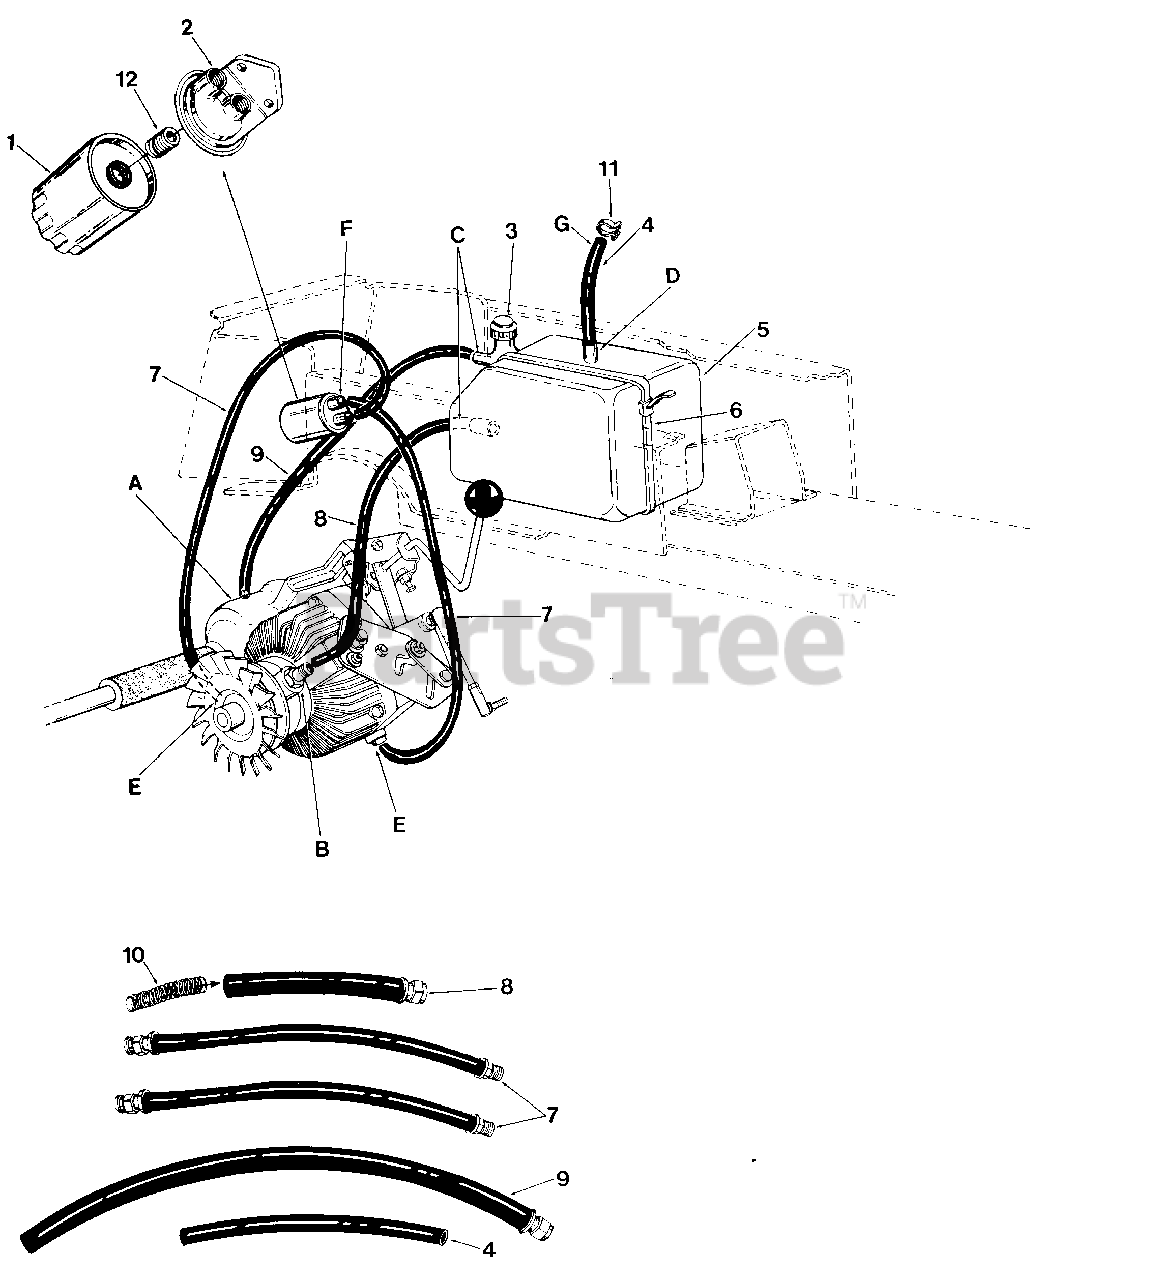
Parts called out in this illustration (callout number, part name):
1	Oil Filter
2	Filter Base
3	Oil Reservoir Cap
4	Gas Line-13" Lg.
5	Oil Reservoir
6	Cable Tie 34.25" Lg.
7	Hose Ass'y. 3/8" I.D. x 16.5" Lg.
8	Hose Ass'y. 5/8" I.D. x 9" Lg.
9	Hose Ass'y. 1/2" I.D.
11	Wire Retainer
12	Plug Expansion 13/16
